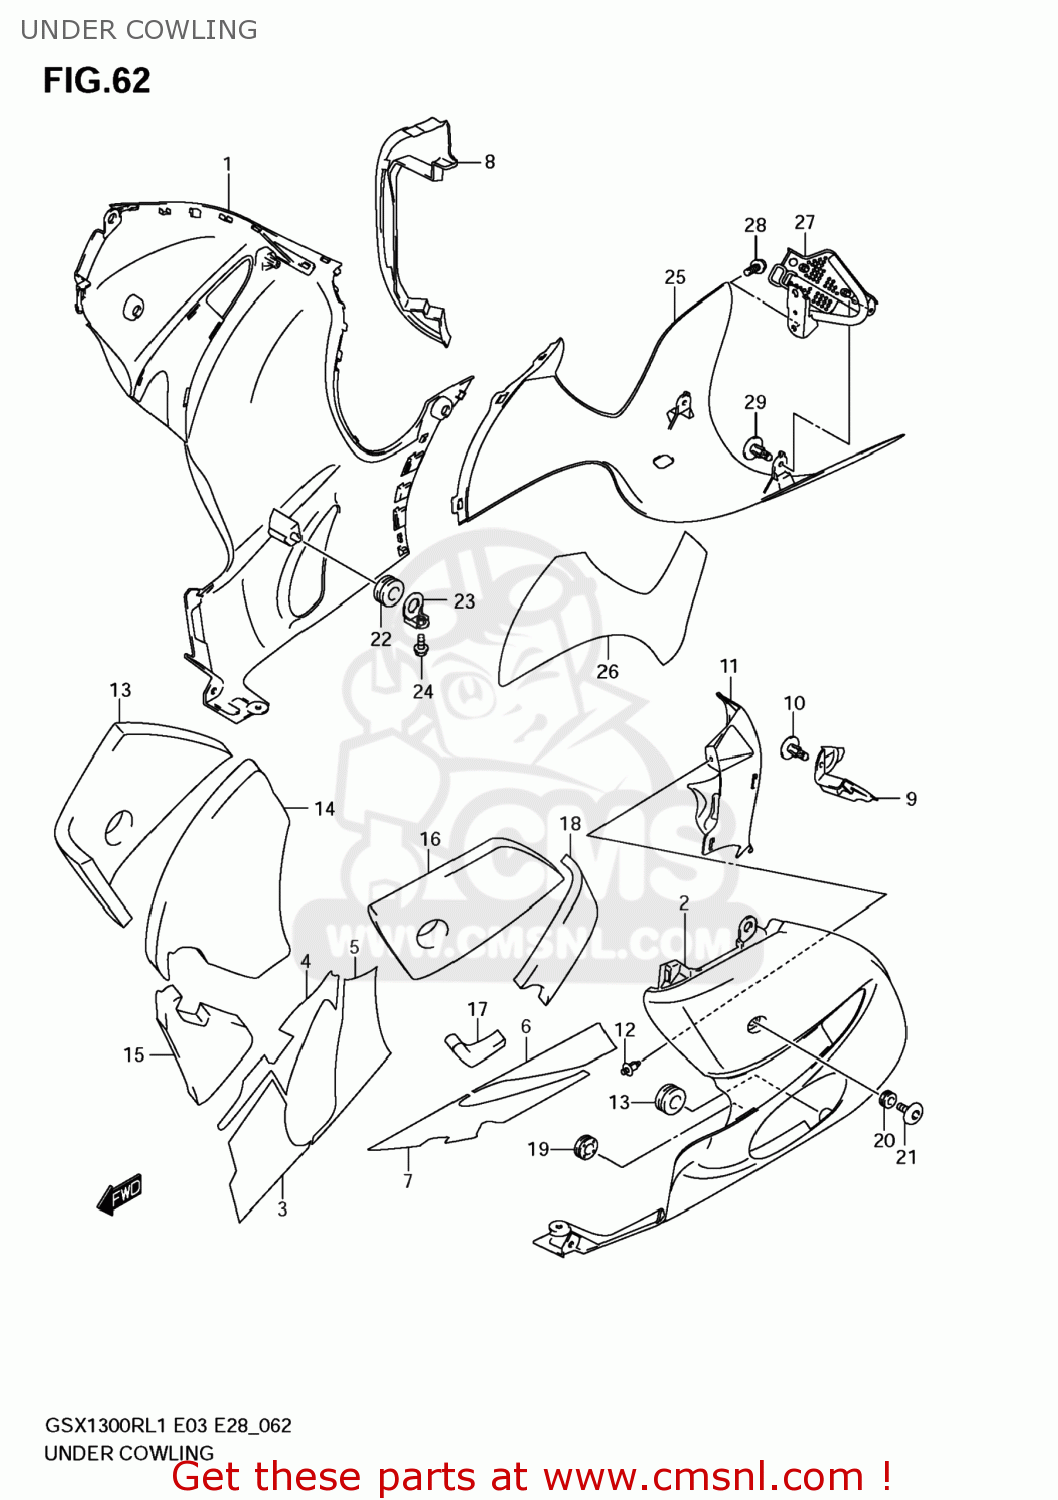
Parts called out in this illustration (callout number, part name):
1	COWLING,UNDER,R(BLUE)
2	COWLING,UNDER,L(BLUE)
3	SHIELD,UNDER COWL HEAT,R NO.1
4	SHIELD,UNDER COWL HEAT,R NO.3
5	SHIELD,UNDER COWL HEAT,R NO.2
6	SHIELD,UNDER COWL HEAT,L NO.1
7	SHIELD,UNDER COWL HEAT,L NO.2
8	PROTECTOR,COWLING UNDER,R
9	PROTECTOR,COWLING UNDER,L
10	CLIP
11	COVER,UNDER COWL,L
12	CLIP(BLACK)
13	CUSHION,UNDER COWLING,R NO.1
14	CUSHION,UNDER COWLING,R NO.2
15	CUSHION,UNDER COWLING,R NO.3
16	CUSHION,UNDER COWLING,L NO.1
17	CUSHION,UNDER COWLING,L NO.2
18	CUSHION,UNDER COWLING,L NO.3
19	CUSHION,UNDER COWLING,L
20	CUSHION
21	SCREW(6X20)
22	CUSHION
23	PLATE,UNDER COWL
24	BOLT
25	COWLING,UNDER RR
26	SHIELD,UNDER COWL HEAT
27	BRACKET,RR UNDER COWLING
28	BOLT
29	CLIP
